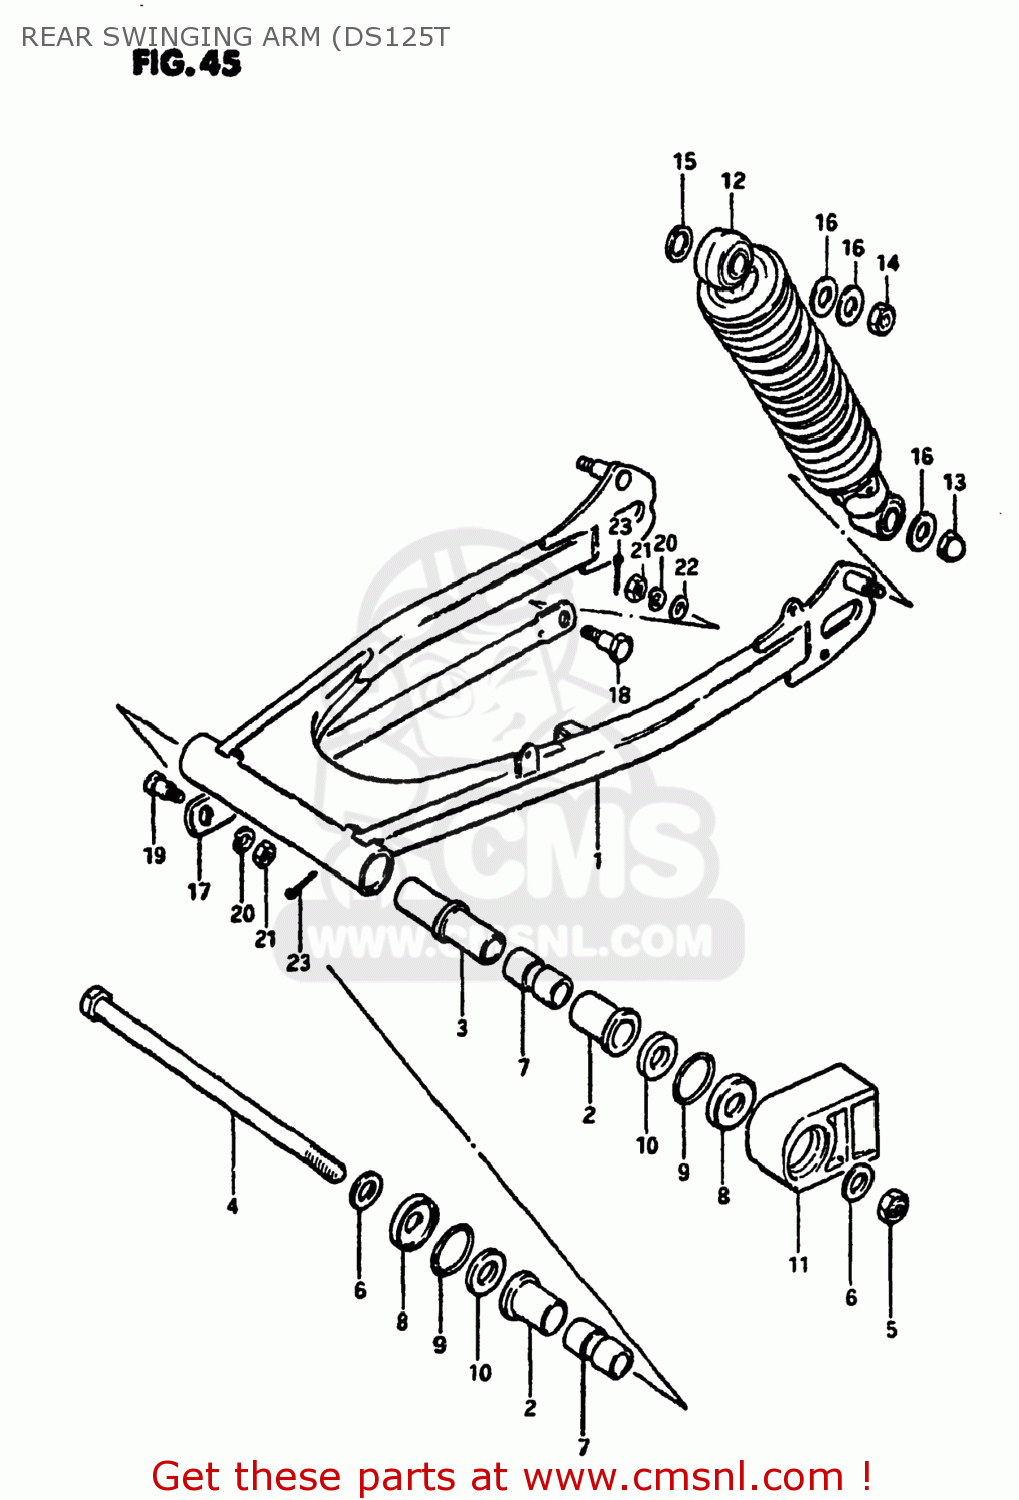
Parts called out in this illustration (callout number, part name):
1	SWING ARM ASSEMBLY,REAR
2	BUSH
3	SPACER,RR SWGARM PIVOT CTR
4	SHAFT,REAR SWING ARM
5	NUT 12MM
6	WASHER
7	SPACER,RR SWGARM PIVOT
8	COVER,SWGARM BUSH DUST SEAL
9	O RING(D:2,ID:24.5)
10	WASHER(12.5X24X2.3)
11	BUFFER,CHAIN TOUCH DEFLECTOR
12	ABSORBER ASSEMBLY,REAR SHOCK
13	NUT, LOWER LH
14	NUT
15	WASHER
16	WASHER
17	TORQUE LINK,REAR
18	BOLT(8X22)
19	BOLT(8X26.5)
20	LOCK WASHER
21	NUT
22	WASHER
23	PIN
